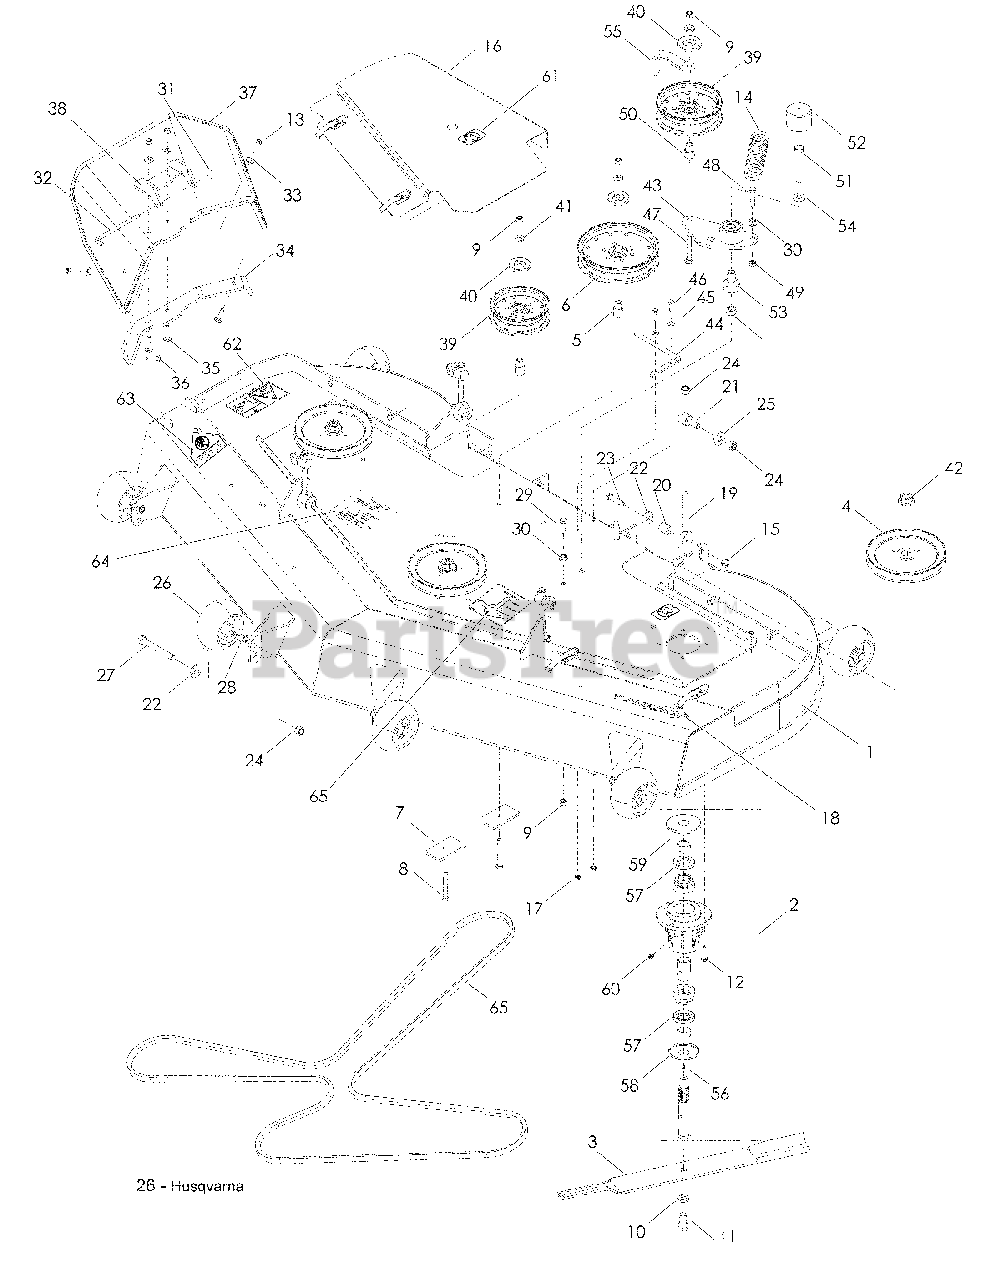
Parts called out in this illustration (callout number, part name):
1	DECK w/ DECALS
2	HOUSING ASSM
5	BUSHING, IDLER
6	PULLEY, IDLER
7	PAD, PAINTED
8	HCS 3/8-16 x 3
9	NUT 3/8-16 HEX NYLOC
10	WASHER 5/8 SLW
11	HCS 5/8-18 x 1¼
12	HCS 5/16-18 x 1¼
13	NUT 5/16-18 HEX NYLOC
15	NUT 7/16-14 HEX CTRLK GR A
16	BELT SHIELD ASSM RT
17	NUT ¼-20 HEX FLANGE
18	DECAL, TUNNELRAM
22	WASHER ½ FLAT
23	HCS 7/16-14 x 1¾
24	NUT ½-13 NYLOC
25	WASHER ½ STD FLT
26	WHEEL, GAUGE
27	HHB ½-13 x 4
28	NUT ½-13 HEX
29	HCS 3/8-16 x 1¼
30	NUT 3/8-16 HEX WHIZLK
31	COTTER PIN 1/8 x ¾
32	PIN, CHUTE PIVOT
33	WASHER 5/16 STD FLT
34	REINFORCEMENT, 72
35	RHSNB 5/16-18 x 1½
36	RHSNB 5/16-18 x 1¼
37	CHUTE, DISCHARGE
38	BRACKET, MOUNTING
39	PULLEY, IDLER
40	SHIELD, DUST
41	WASHER 3/8 SPECIAL
42	NUT ¾-16 FLANGE
43	ARM, IDLER w/ BEARINGS
44	GUIDE, BELT
45	WASHER ¼ STD FLT
46	HCS ¼-20 x 1
47	RHSNB 3/8-16 x 2¾
48	HCS 3/8-16 x 1½ GR 8
49	NUT 3/8-16 HEX JAM
50	BUSHING, IDLER
51	HCS ½-13 x 3¼
52	CAP, VINYL
53	BEARING, PIVOT
54	WASHER, BELLEVILLE
55	GUIDE, BELT
57	SEAL, SHAFT
58	DUST CAP, BOTTOM
59	DUST CAP, TOP
60	POPPET, GREASE
61	DECAL, NO STEP
62	DECAL, SEVERING
63	DECAL, WARNING
64	DECAL, ANTI-SCALP
65	DECAL, BELT ROUTING
66	BELT, DECK
